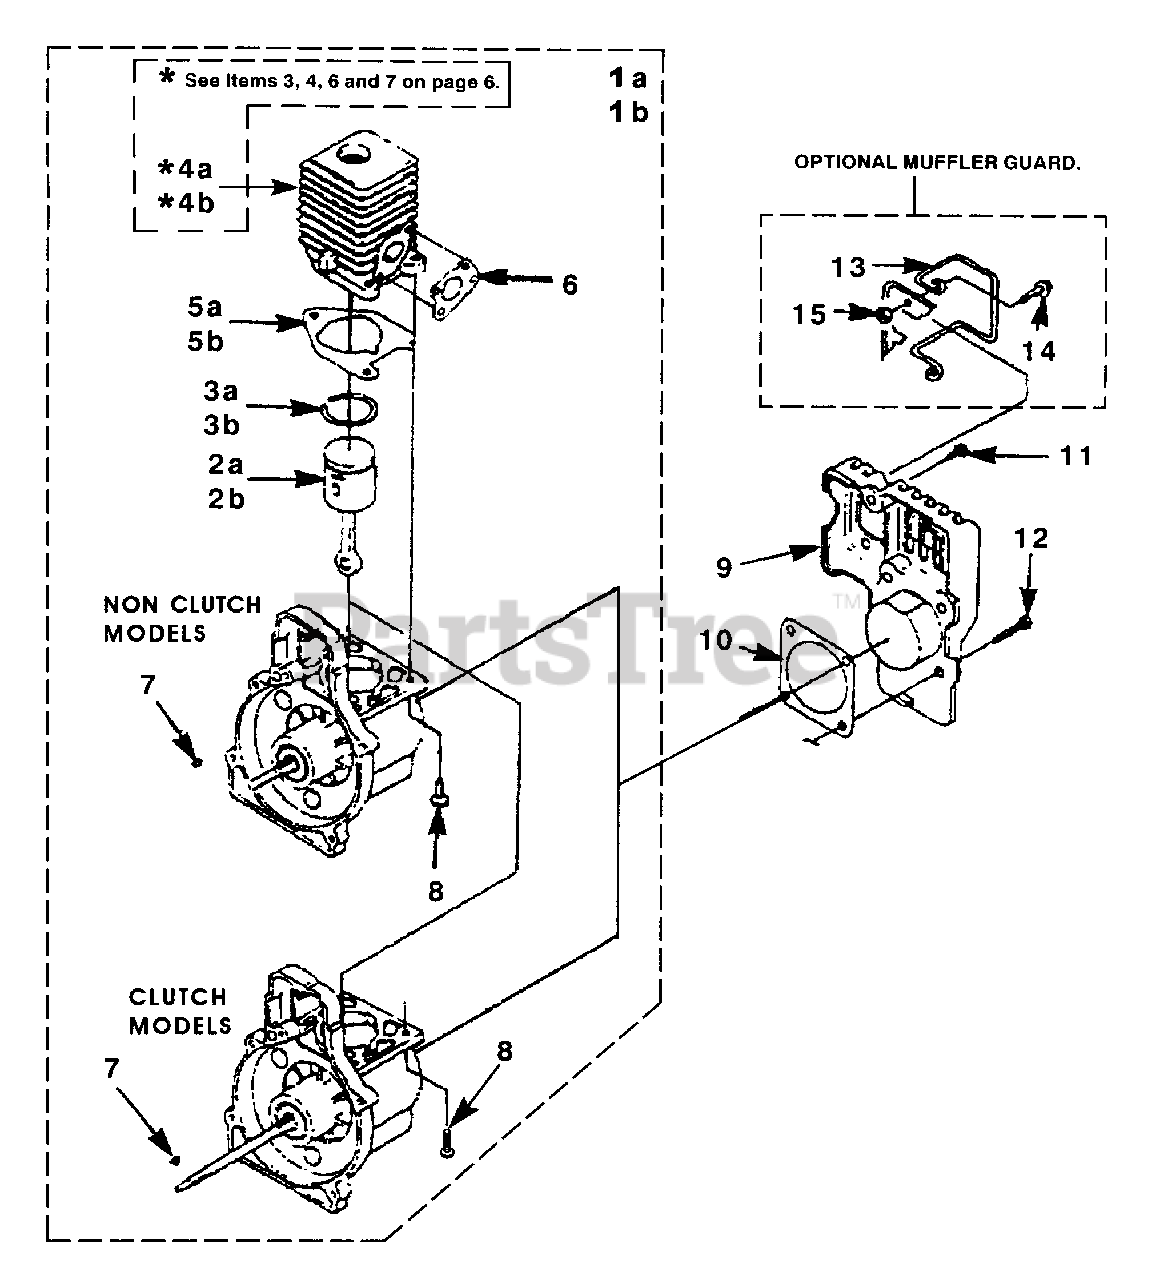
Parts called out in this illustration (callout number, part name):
6	GASKET - Heat Dam
7	KEY - Woodruff
8	SCREW - Thread Forming (10-24 X 3/4")
9	CRANKCASE COVER
10	GASKET - Crankcase Cover
11	SCREW - Plastite (#10 X 1/2")
12	SCREW - Taptite (10-24 X 1/2")
13	WIRE GUARD KIT
14	SCREW - Hex Sems (10-24 X 1/2")
15	NUT (10-24)
